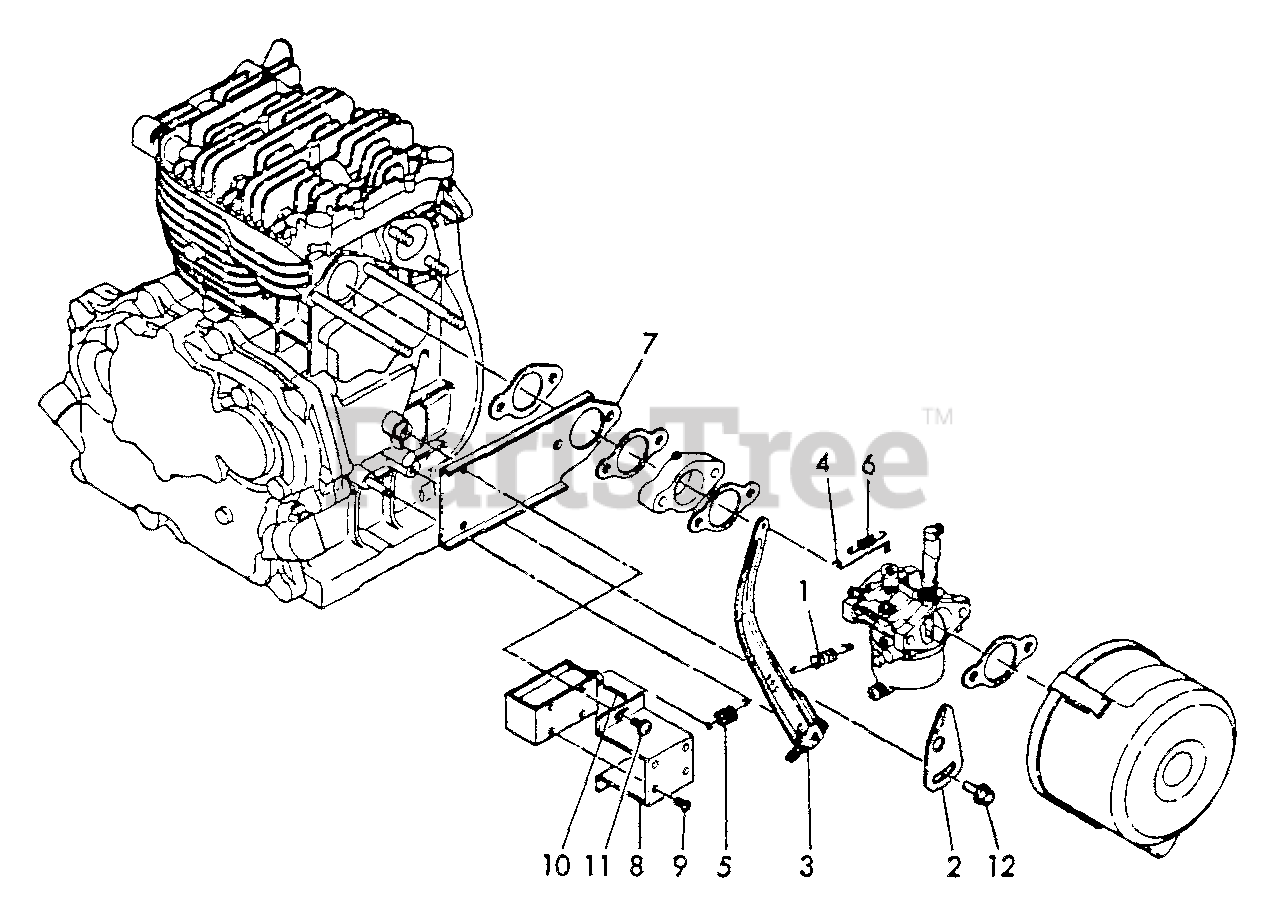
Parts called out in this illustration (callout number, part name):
1	SPRING, REGULATOR
2	HANDLE, REGULATOR
3	LEVER, GOVERNOR
4	LINK, THROTTLE
5	SPRING
6	SPRING
7	MOUNT, SOLENOID
8	HOLDER, SOLENOID
9	SCREW - 3X4
10	PIN, SPLIT - 2.5X20
11	SCREW - 5X10
12	BOLT - 6X8 -- PLATED
